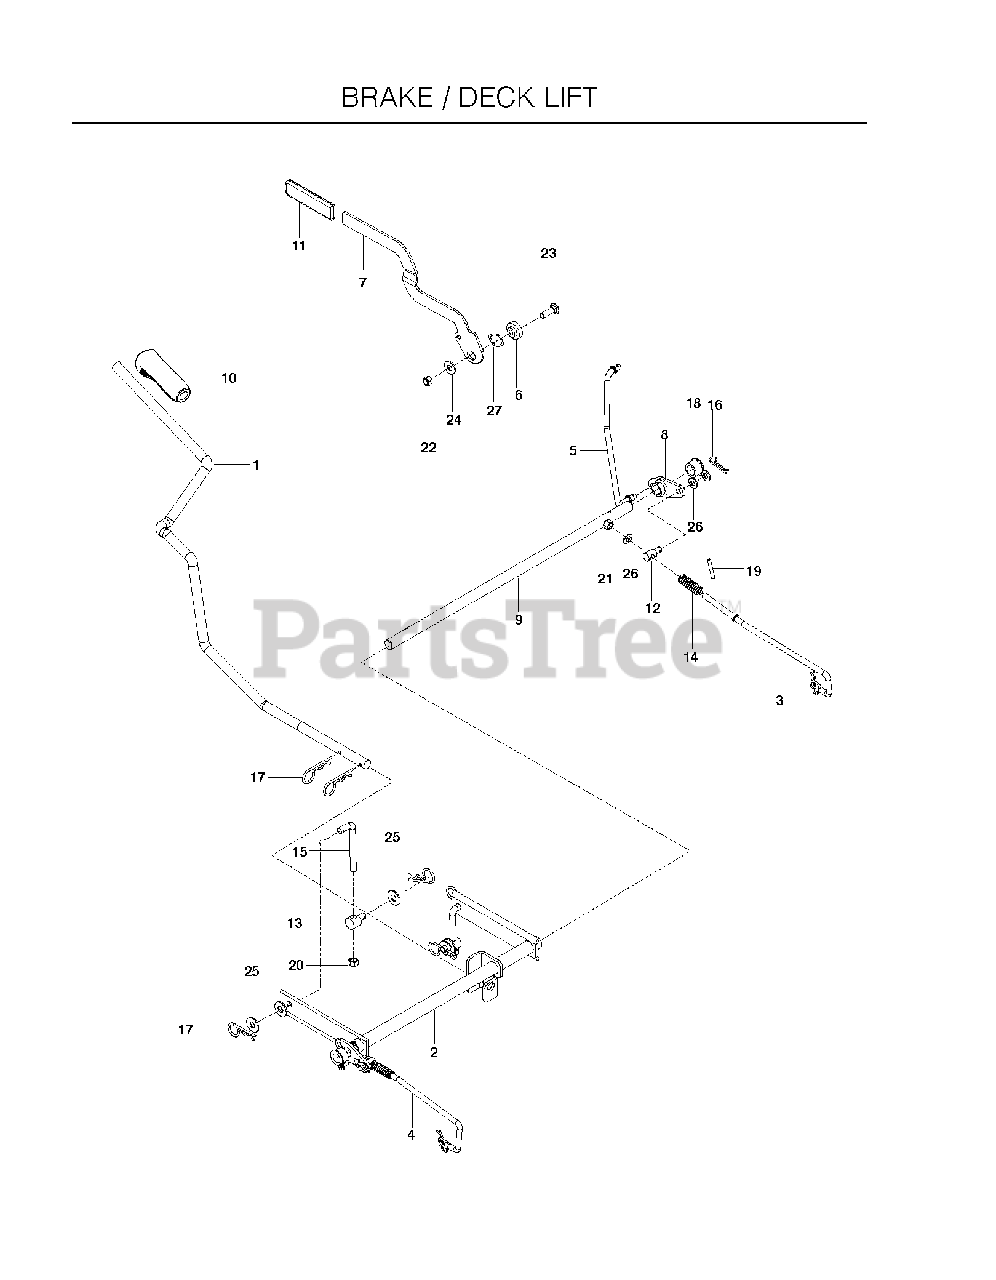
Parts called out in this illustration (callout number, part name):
1	ARM, LIFT HANDLE, BLK
2	WLDMT.LIFT.SHAFT.BLACK
3	LINKAGE, EZT BRAKE RT
4	LINKAGE, EZT BRAKE LT
5	LINKAGE, BRAKE, UPPER
6	BRAKE ARM PIVOT
7	HANDLE, BRAKE, BLK
8	BELLCRANK, BRAKE
9	ROD, BRAKE
10	GRIP.LEVER.5625.ID
11	GRIP BRAKE HANDLE
12	BRAKE SWIVEL
15	L-ROD 3.5
16	HAIRPIN #2
17	HAIRPIN #4
18	PLASTIC BUSHING
19	ROLL PIN 3/16 X 1-1/4 ZD
20	NUT 3/8-16 NYLOC
21	NUT 5/16 NYLOC
22	NUT HEX 3/8-16 NYLON, THIN
23	RHSNB 3/8-16 X 1-1/4
24	WASHER, 7/16 DISC SPRING
25	WASHER 3/8 FLAT
26	FLAT WASHER 5/16 SAE
27	WASHER, .825 X 1.087, WAVE
